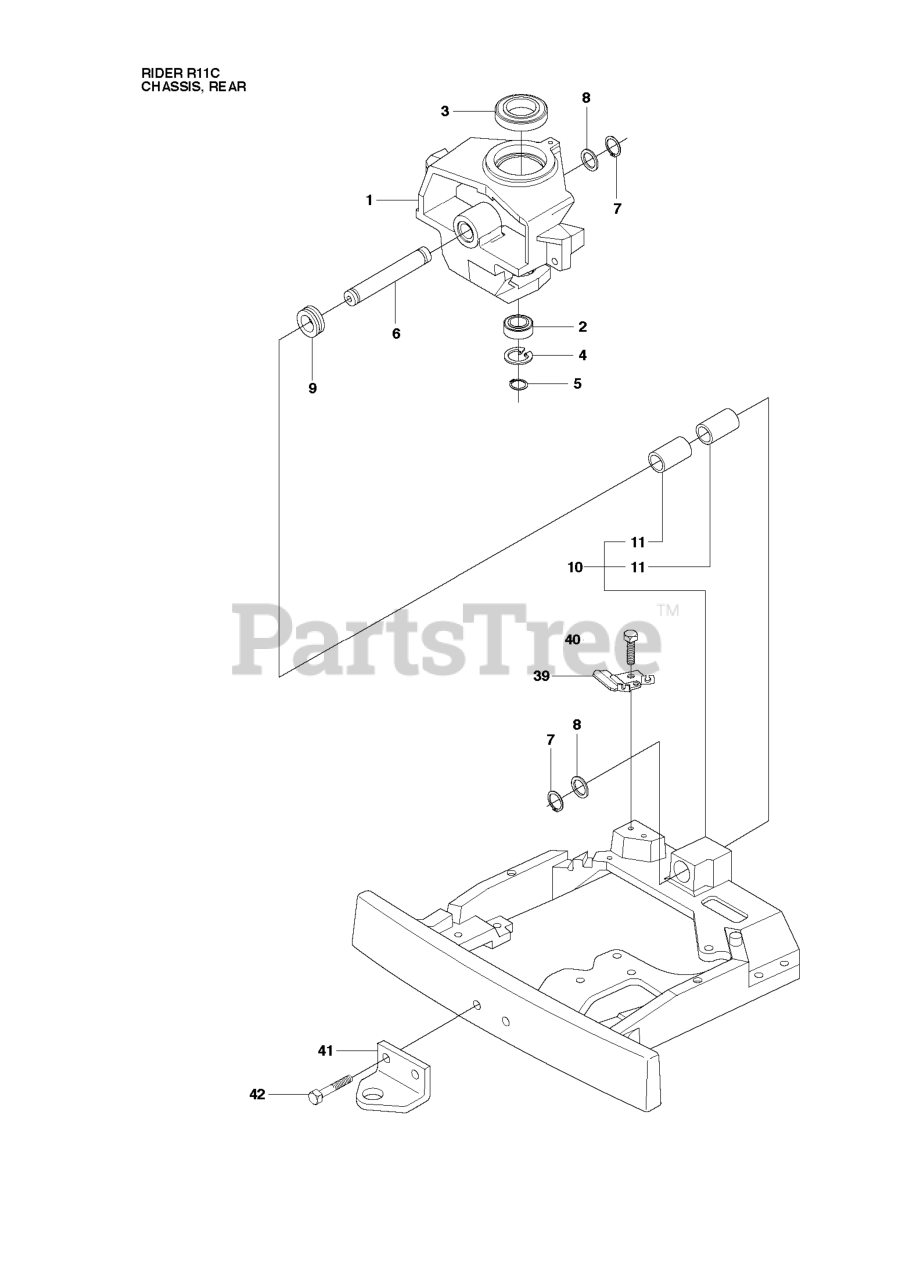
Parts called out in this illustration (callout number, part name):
2	Ball Bearing 6005-2rs
3	BALL BEARING 6010 2RS1
4	CIRCLIP SGH 47
5	RETAINING RING SGA 25
7	RETAINING RING SGA 25
42	Screw M10x25
